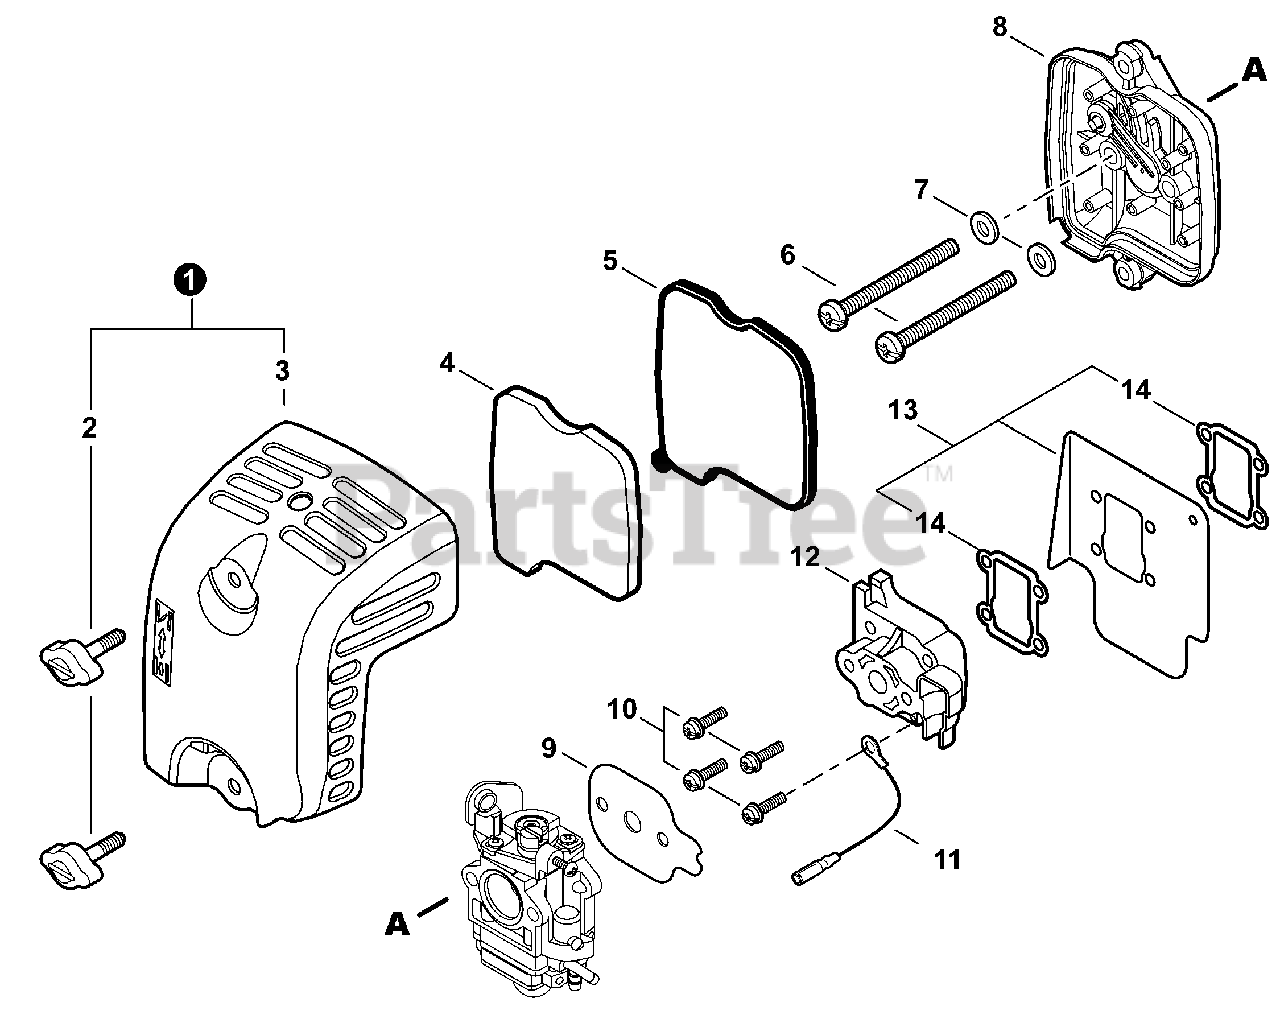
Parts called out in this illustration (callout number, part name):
1	COVER ASSY, AIR FILTER
2	THUMBSCREW
3	COVER, AIR FILTER
4	PRE-FILTER, FOAM
5	FILTER, AIR
6	SCREW M5×60
7	WASHER 5.5×12×0.8
8	CASE ASSY, AIR FILTER
9	GASKET, CARBURETOR
10	SCREW M5×25
11	LEAD - GROUND L= 110mm
12	INSULATOR WITH REED VALVE
13	SHIELD ASSY, INTAKE HEAT
14	GASKET, EXHAUST
